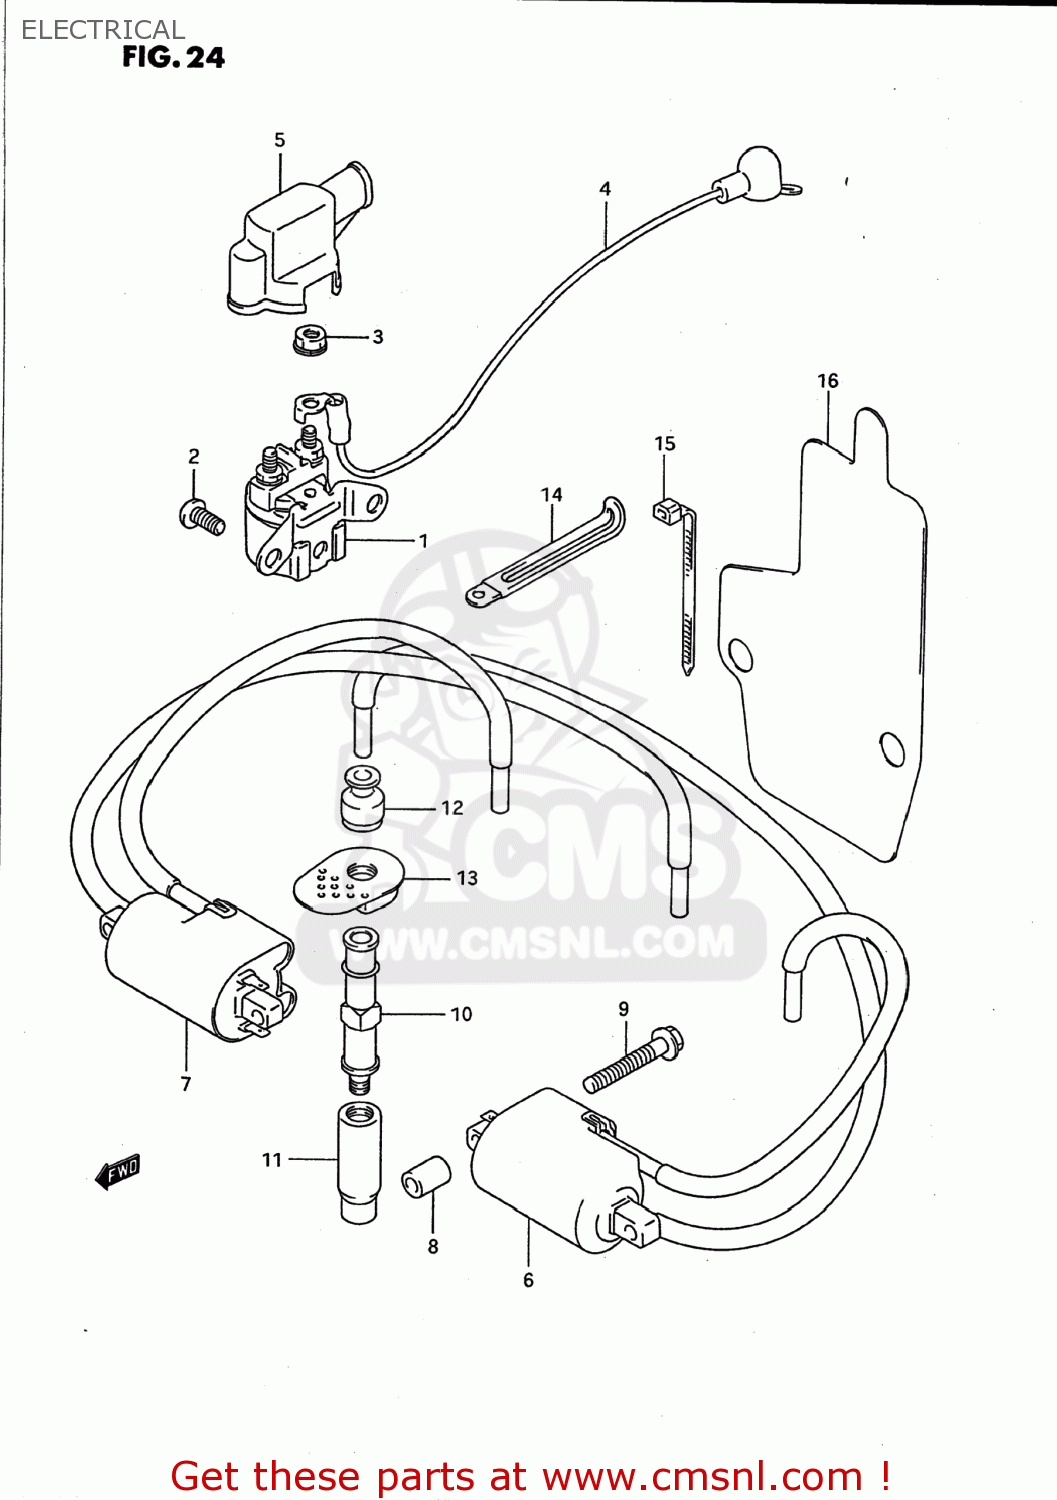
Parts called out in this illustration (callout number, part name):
1	RELAY ASSY,STARTING MOTOR
2	SCREW
3	NUT
4	WIRE,STARTER MOTOR LEAD
5	CAP,STARTER RELAY
6	COIL ASSEMBLY,IGNITION NO
7	COIL ASSEMBLY,IGNITION NO
8	SPACER(6.2X12X16)
9	SCREW
10	CAP,SPARK PLUG
11	SEAL,SPARK PLUG
12	SEAL,HIGH TENSION CORD
13	COVER,SPARK PLUG CAP
14	CLAMP
15	CLAMP(L:165)
16	COVER,IGNITION COIL
